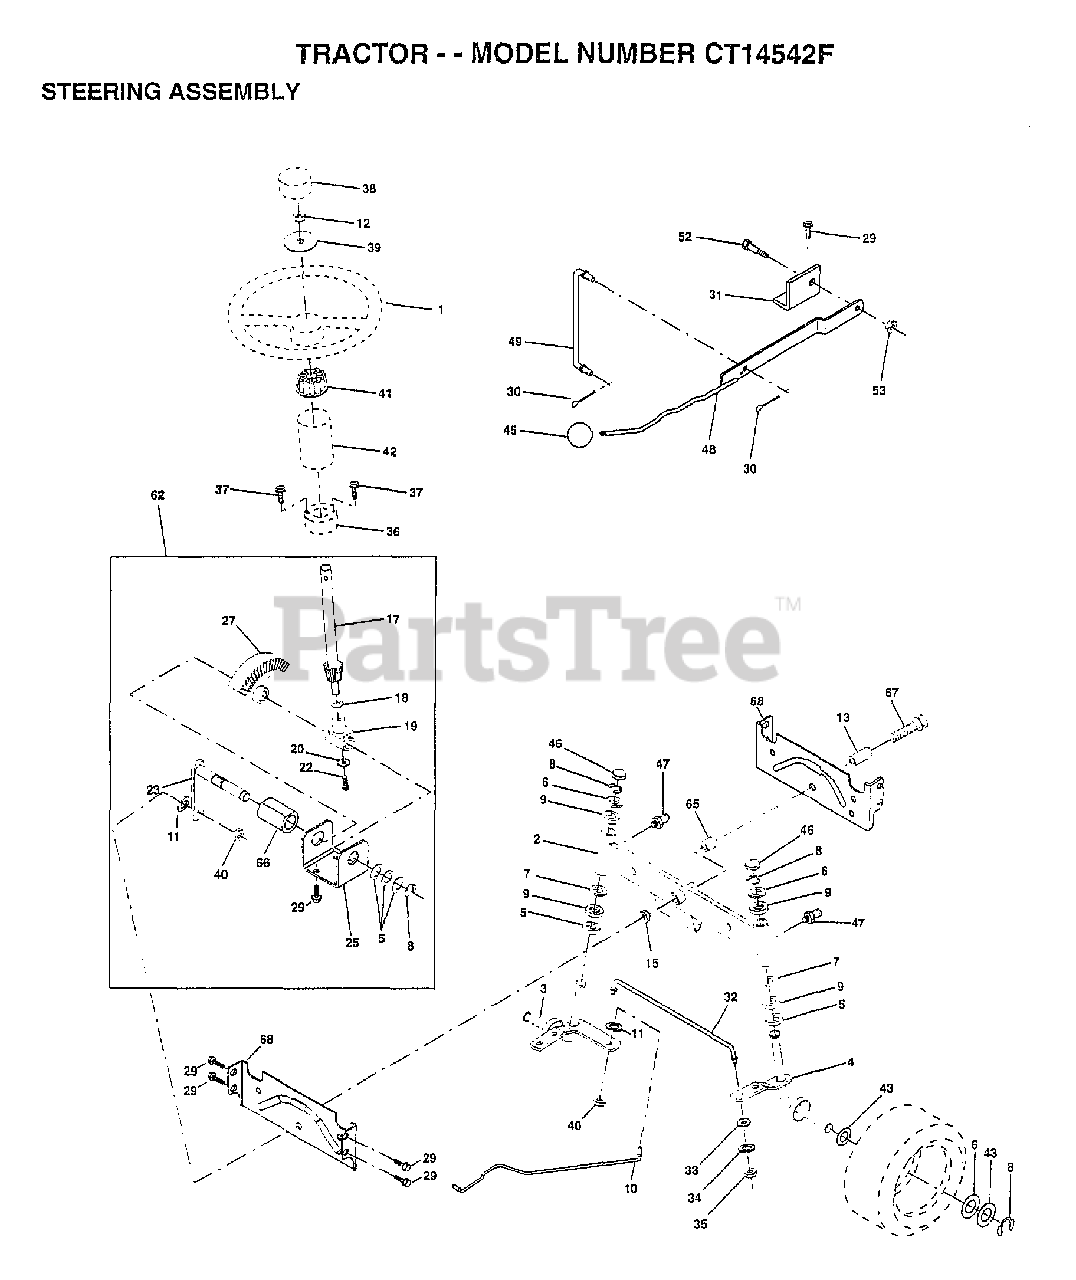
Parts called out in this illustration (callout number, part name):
1	WHEEL STR AYP BLK
2	AXLE ASM
3	SPINDLE.ASM.LH
4	"SPINDLE ASM,RH"
5	WASHER .T
6	WASHER
7	WASHER
8	RING
9	COL. SRTG. BEAR.
10	DRAGLINK-STAMPED
11	LOCKWASHER
13	BEARING AXLE
15	"NUT-LOC,FLANGE LT"
17	SHAFT ASM STEERNG
18	THRUST WASHER
19	SUPPORT.SHAFT
22	SCREW HEX SOC1/4-
25	BRKT-STEERING
27	GEAR SECTOR
29	SCREW
30	COTTER PIN
31	BRKT.PVT.MAN.LVR.
32	ROD.TIE.19.75
33	WASHER M
34	LOCKWASHER
35	NUT.LOCK.5/16-24
36	BUSHING.STRG.3/4
37	"SCREW-TT,10-32 FL"
38	CAP STEER AYP
39	WASHER
40	GRIPCO NUT
41	ADAPTER LT
42	BOOT SHAFT STEER
43	WASHER
45	KNOB.RD.7/16-14
46	CAP
47	ZERK M
48	LEVER.ASM.CLUTCH
49	LINK CLTCH W/NUTS
52	"BOLT, SHOULDER LT"
62	KIT STEERING ASM
65	SPACER AXLE
66	"BEARING-ARM,PITMA"
67	BOLT
68	BRACE AXLE
